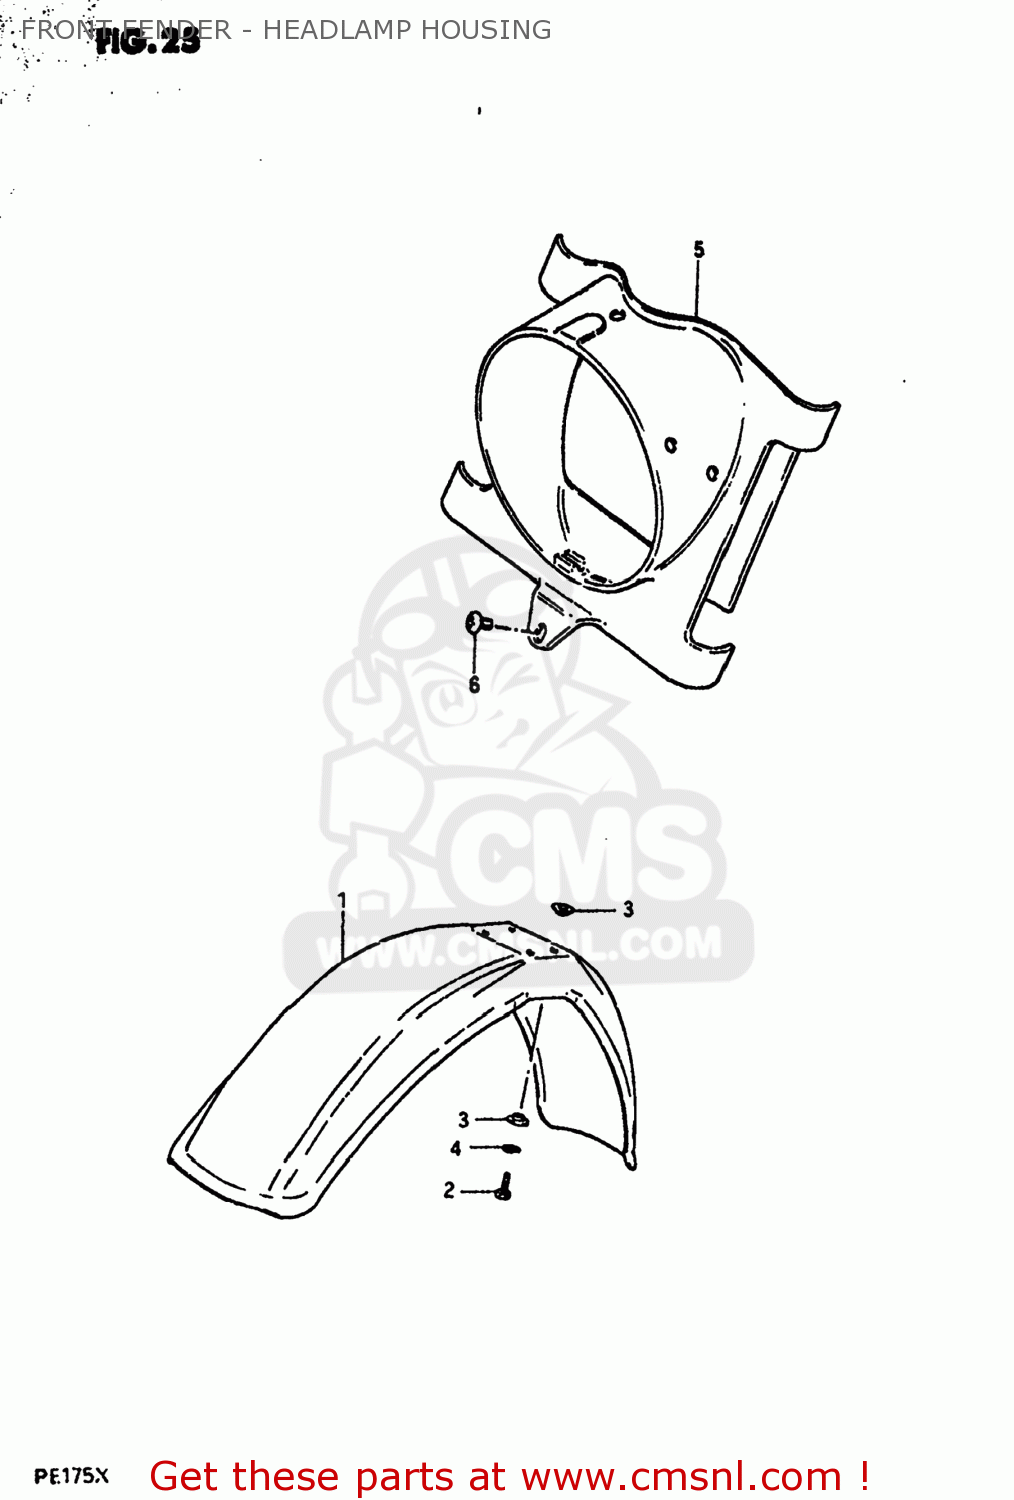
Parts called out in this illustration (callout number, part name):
1	FENDER,FRONT
2	BOLT, UPPER
3	WASHER
4	LOCK WASHER
5	HOUSING,HEADLAMP
6	SCREW
